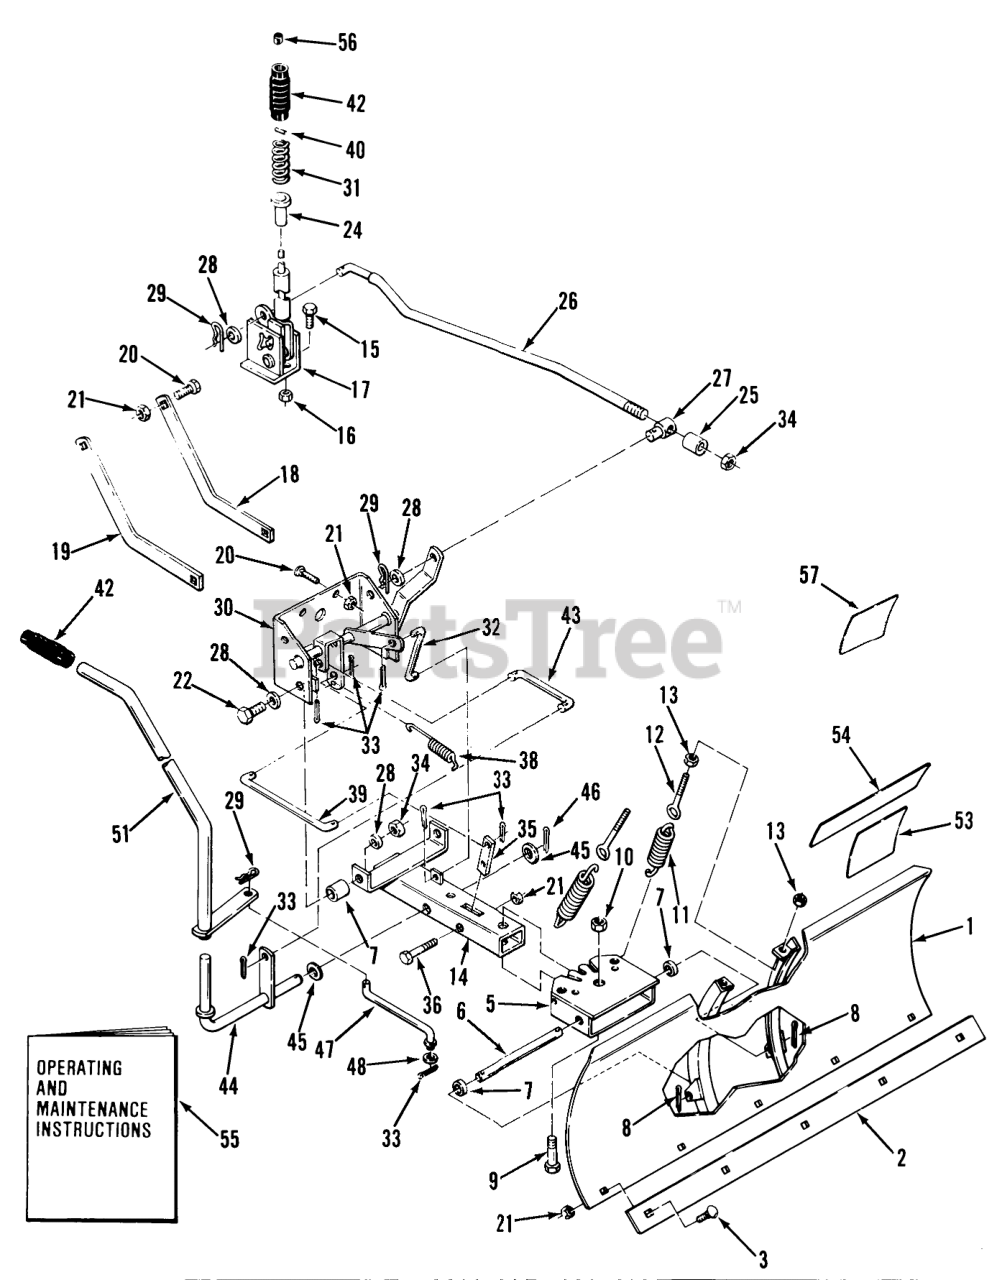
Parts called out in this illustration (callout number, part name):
1	Blade
2	Plate
3	Bolt-Carriage
5	ASSY-QUADRANT R
6	ROD-LOWER
7	Spacer
9	HEX HD CAP SCREW
10	Nut
11	SPRING
12	EYEBOLT
13	Nut
14	ASS'Y-FRAME R
15	Bolt-Carriage
16	Nut
17	ASS'Y-LIFT HANDLE R
18	BRACE-RH R
19	Brace-RH
20	Bolt
21	NUT
22	Hhcs
24	RETAINER-SPRING
25	Spacer
26	Rod
27	TRUNION
28	Washer
29	Hairpin
30	ASS'Y-BELLCRANK L R
31	SPRING-COMPRESSION
32	Rod
33	Pop Rivet
34	Nut
35	LATCH-QUADRANT R
36	HHCS
38	SPRING
39	ROD-LATCH
40	PIN-SPIROL
42	HANDGRIP
43	ROD-BELLCRANK
44	Handle Pivot
45	Washer
46	Cotter Pin
47	ROD-ANGLING
48	Washer
51	ASSY-HANDLE R
53	DECAL-CAUTION
54	DECAL WHEEL HORSE
55	Operating and Maintenance Instructions
56	CAP-ROD, PLUNGER
57	Decal-VIN Overlay
